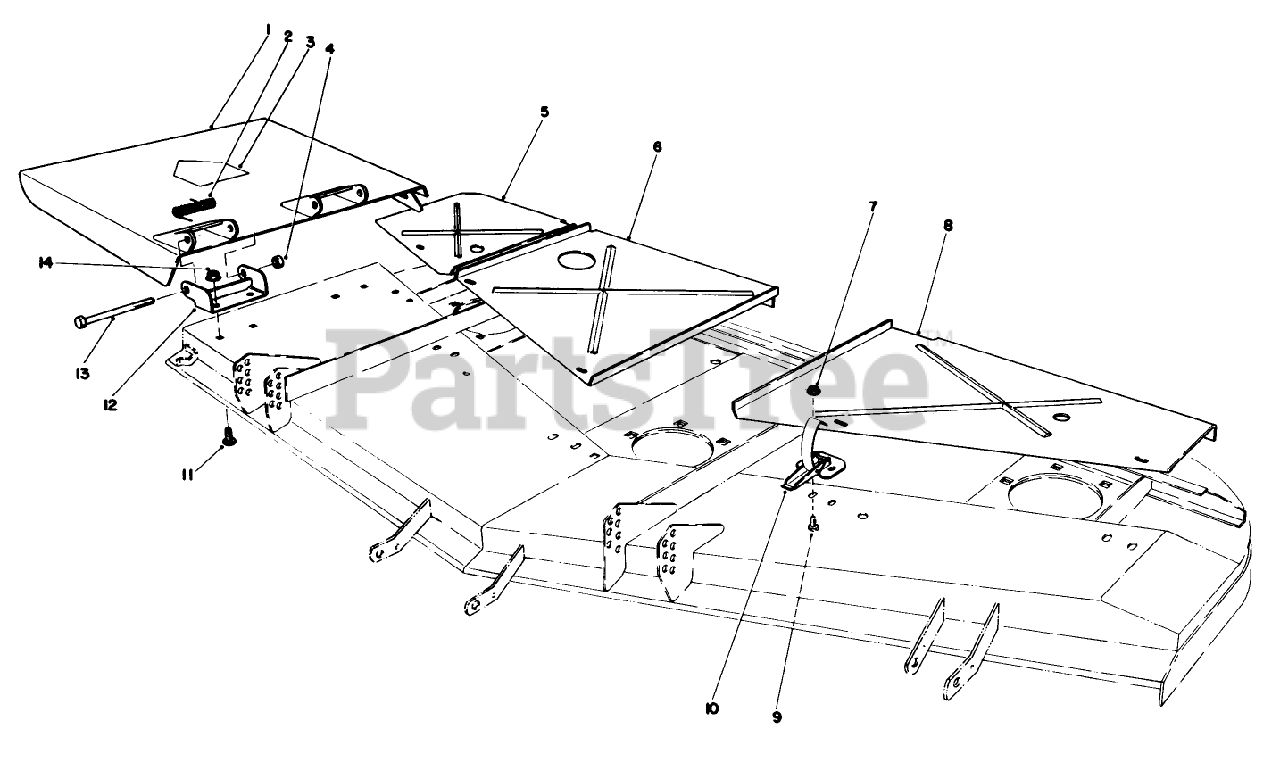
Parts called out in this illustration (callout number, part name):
1	Deflector Assembly (Incl. Ref. #3)
2	SPRING
3	DECAL-DANGER
4	NUT-HEX
5	Cover-Deck R.H.
6	Cover-Deck Center
7	NUT-LOCK, FLANGE
8	Cover-Deck L.H.
9	SCREW-HWH
10	CLAMP-SLOTTED
11	SCREW-CARR
12	Bracket-Hinge
13	SCREW-HH
14	NUT-HHF, WHIZ
